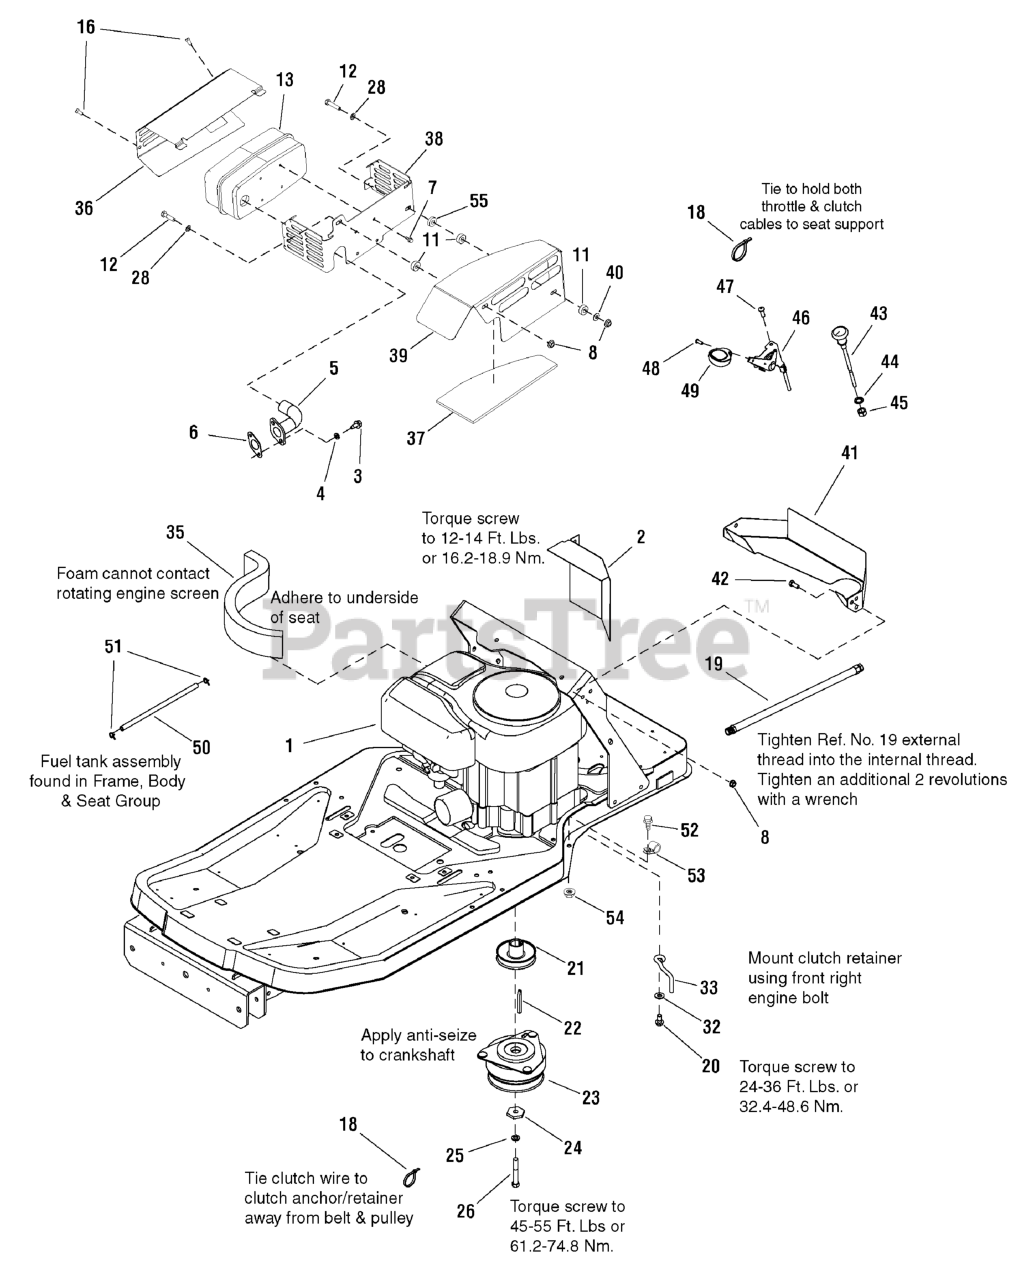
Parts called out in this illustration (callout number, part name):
1	* ENGINE, 20HP B&S
2	HEAT SHIELD, Inner
3	CAPSCREW, Hex Head, 5/16-18 x 3/4, G8
4	LOCKWASHER, Spring, 5/16
5	PIPE ASSEMBLY, Exhaust
6	GASKET, Exhaust
7	SCREW, Hex Whiz Lock Flange, 1/4-20 x 5/8
8	NUT, Hex Whiz Lock Flange, 5/16-18
11	SPACER, .390 ID x .9 OD x .34 LG, Powdered Metal
12	CAPSCREW, Hex Head, 5/16-18 x 1-3/4, G5
13	MUFFLER ASSEMBLY, Single
16	CAPSCREW, Thread Cutting, # 10 x 1/2
18	TIE, Self Locking, 3-5/8 LG
19	HOSE, Oil Drain, 16-1/2 LG
20	SCREW, Taptite Washer Head, 3/8 - 16 x 1-1/4
21	PULLEY ASSEMBLY, Engine
22	KEY, Hi-Pro, 1/4 x 2-1/2
23	CLUTCH, Electric
24	WASHER, Hex, .453 ID x 1-1/2
25	LOCKWASHER, Spring, .438
26	CAPSCREW, Hex Head, 7/16-20 x 3, G5
28	WASHER, 5/16
32	WASHER, 3/8, .41 ID x .87 OD x .08 THK
33	RETAINER, Clutch
35	SEAL, Foam Air Duct, 1 x 2-1/2, 12" LG
36	HEAT SHIELD, Single
37	INSULATION SHIELD, Top Muffler
38	MUFFLER BRACKET/HEAT SHIELD
39	GUARD, Muffler
40	NUT, Push Pal, 5/16
41	AIR DUCT, Inlet
42	CAPSCREW, Hex Head, 5/16-18 x 3/4, G5
46	CONTROL, Throttle
47	SCREW, Pan Head Taptite Torx, 1/4-20 x 5/8
48	SCREW, Pan Head Taptite Combo, 310-16 x 3/4
49	KNOB, Throttle
50	HOSE, Fuel, 19.5"
51	CLAMP, Hose
52	CAPSCREW, Hex Whiz Lock Flange, 5/16 - 18 x 3/4
53	CLIP, Harness
54	NUT, Hex Whiz Lock Flange
55	SPACER, .390 ID x .9 OD x .70 LG
